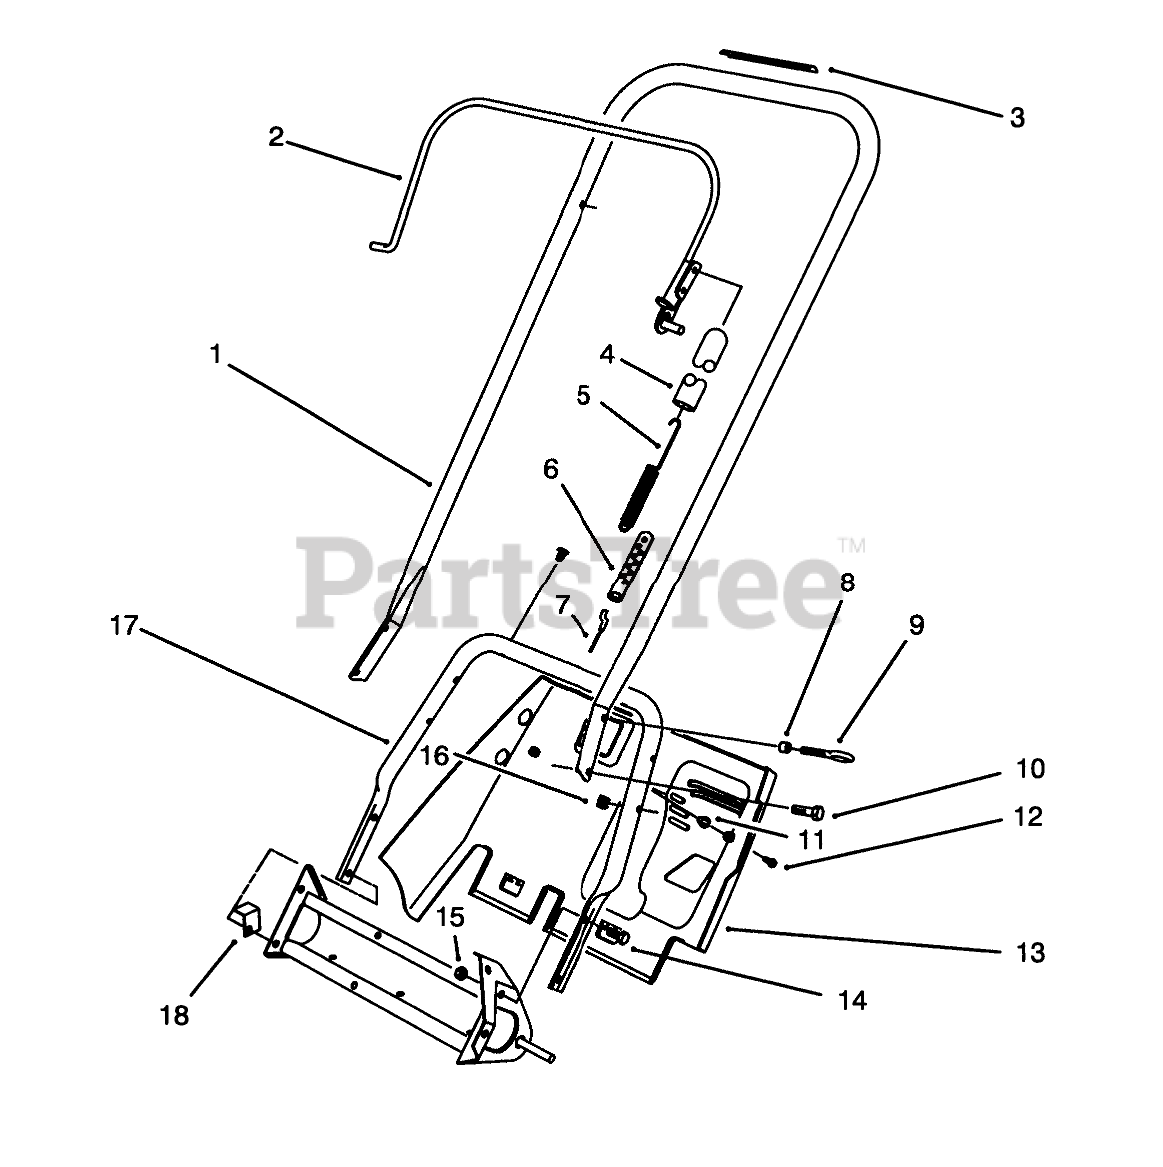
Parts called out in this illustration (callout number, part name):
1	Handle-Upper
2	Bail
3	DECAL - ROTOR DRIVE
4	COVER-SPRING
5	SPRING-CLUTCH
6	ADJUSTER-CABLE, CLUTCH
7	CABLE-CLUTCH
8	SPACER-BLADE, ROTOR
9	EYEBOLT
10	SCREW-HEX HD SLOT
11	EXPANSION TYPE FASTENER
12	SCREW-SHWH, THREAD FORMING
13	LOWER SHROUD
14	SCREW-HH
15	NUT-LOCK, NI
16	TINNERMAN NUT
17	Handle-Lower
18	SHROUD BRACKET
